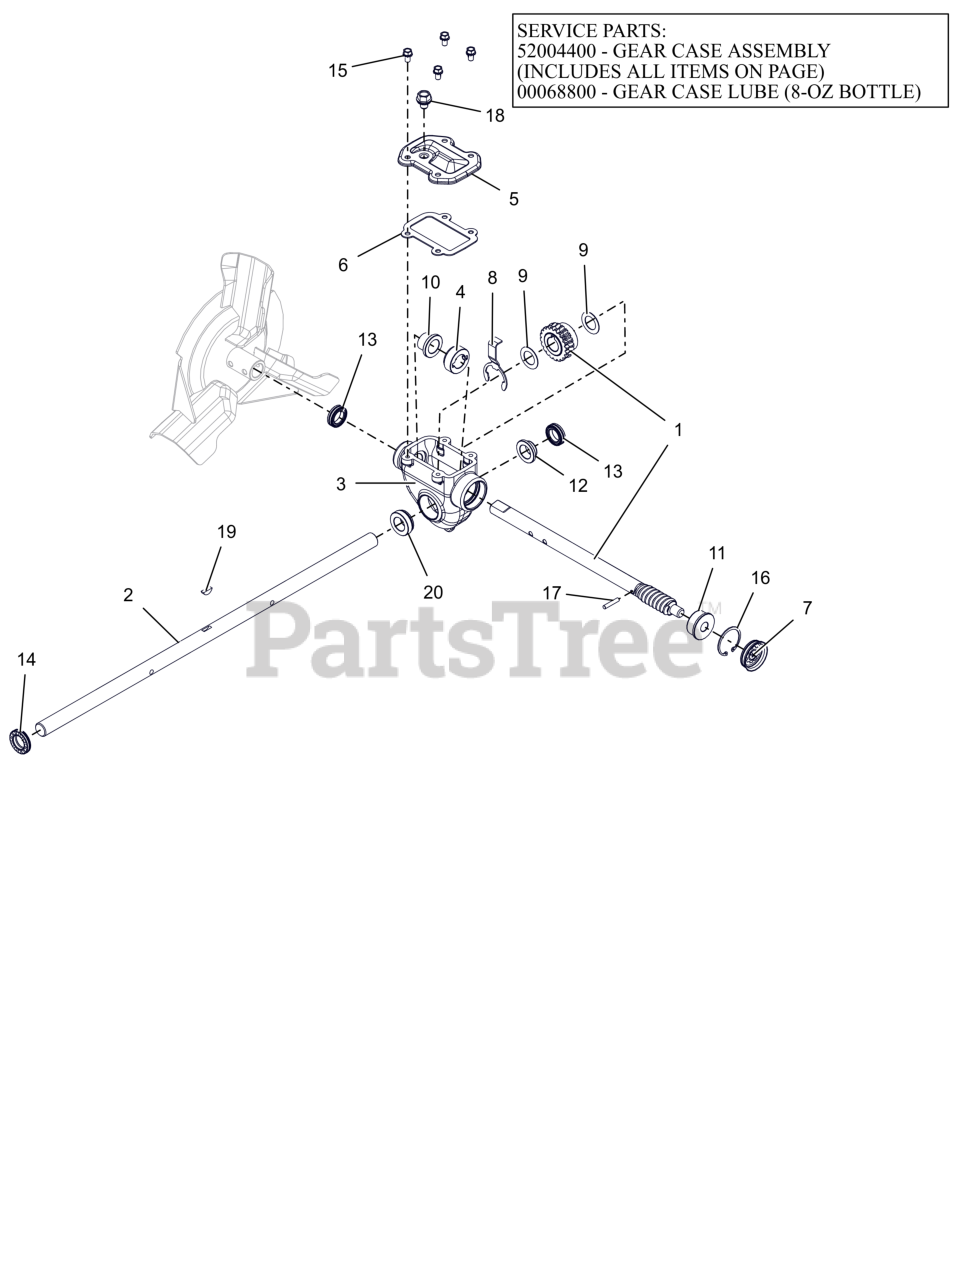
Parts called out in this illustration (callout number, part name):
1	SHAFT AND WORM GEAR ASSEMBLY
2	SHAFT, RAKE - 24" (.750 DIA)
3	GEARCASE, COMPACT MACHINED
3	GEAR CASE, 24" IRON SM TOP-LD
3	ARIENS L3 LUBE, 8 OZ BOTTLE
4	THRUST COLLAR, .75" ID SLIPFIT
5	COVER, TOP - COMPACT
6	GASKET, TOP - COMPACT GEARCASE
7	COVER, GEAR CASE 1.50"
8	BUSHING RETAINER, COMPACT
9	WSHR, FLT .760X1.225X.032 ZCC
10	BSHG-FLG .755X.878X.75X1.25
11	BSHG-FLG .503X1.303X.62X1.465
12	BSHG-FLG .755X.878X.424X1.25
13	SEAL-OIL .748X1.125X.312 TBC29
14	SEAL-OIL .748X1.300X.250 TBC29
15	BLT, SEMS .25-20X.50 G5 ZCC
16	RG-RTNG-INT 1.500X.050
17	PIN-STR .188X1.00 6150
18	SCR, .380-15X.500 W/SEAL WASHER
19	KEY-WDRF .19X.63 HRD #61
20	BSHG-FLG COMPACT, RIGHT
